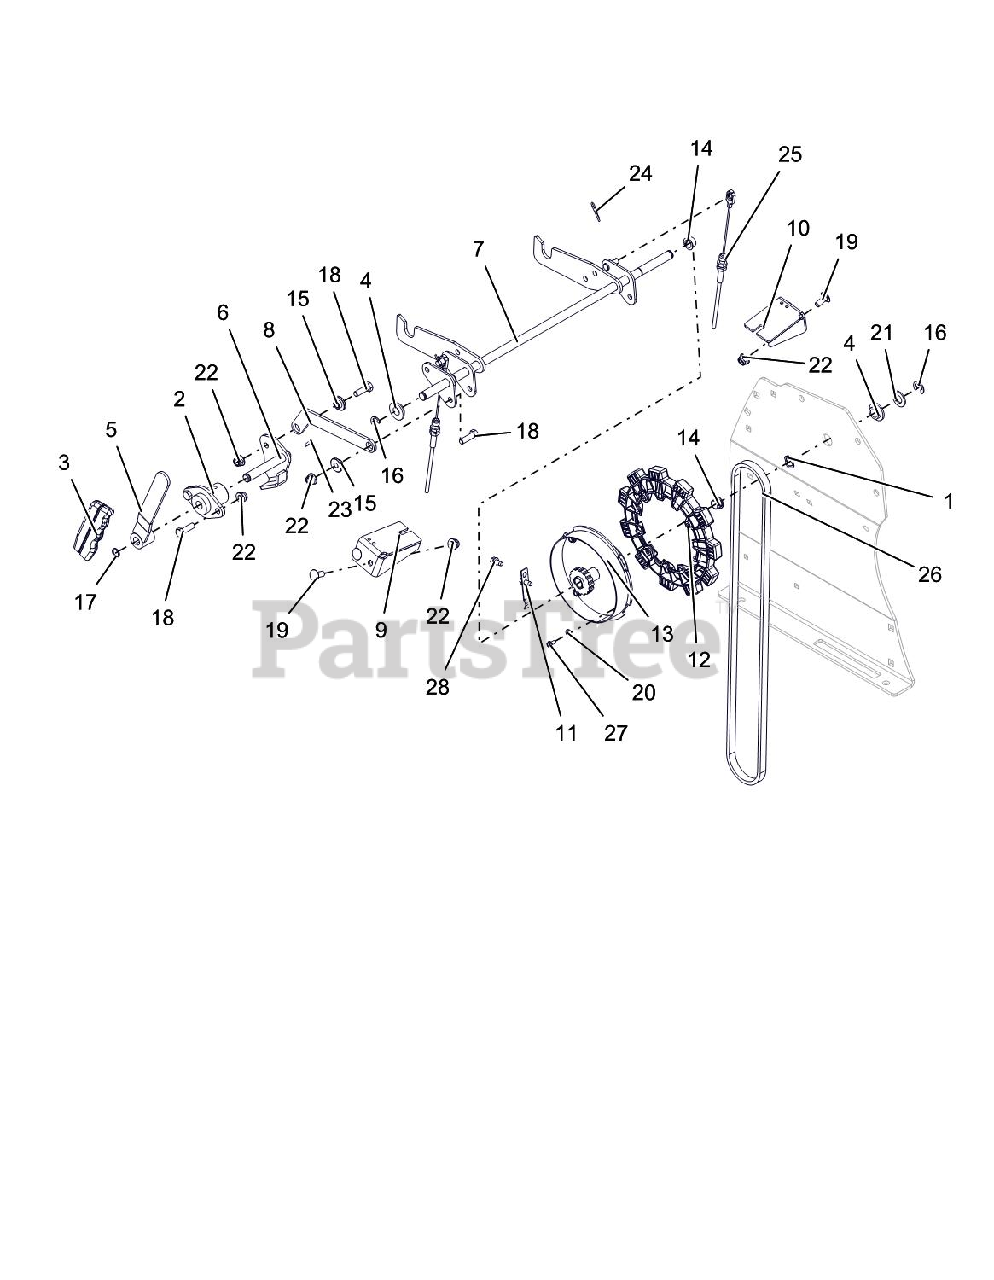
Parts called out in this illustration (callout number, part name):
1	WAVE WASHER .531X.781X.125FH
2	BUSHING, FLANGED
3	GRIP, PARKING BRAKE (YELLOW)
4	BSHG-FLG .515X.750X.310X1.120
5	WMT, PARKING BRAKE HANDLE
6	WMT, PARKING BRAKE ACTUATING
7	WLDMT, PARKING BRAKE/INTERLOCK
8	LINK, BRAKE INTERLOCK
9	BRKT, BRAKE CABLE MTG
10	BRKT, LH CABLE MTG
11	ARM, HOC DETENT
12	WHEEL, HOC
13	KIT, 48-60" HOC WLDMT W/DECAL
14	BUSHING, POLYLINER-.50 SPLIT
15	BSHG-FLG .32X.500X.344X.880
16	RG-RTNG-EXT .500X.042 (E)
17	RG-RTNG-EXT .500X.050 (SNAP)
18	@BLT-HEX .31-18X1.00 GR5 YWZC
19	@BLT-RDHDSQNK .31-18X.75 G5YZ
20	@WSHR-FL-STL.219X.50X.049 YWZC
21	WSHR-FL-NYL .518X1.000X.080
22	@NUT-LK-NYL-FLG .31-18 YWZC
23	KEY-WDRF .13X.63 HRD#5
24	PIN-HAIR INT .08X.18X1.18 YWZC
25	CABLE, PROSTANCE P.BRAKE
26	BELT, TIMING LONG
27	SCR-TAP 10-24X.375 PRE-COAT 80
28	SCR-TAP .25-20X.50 HWH TR YWZ
